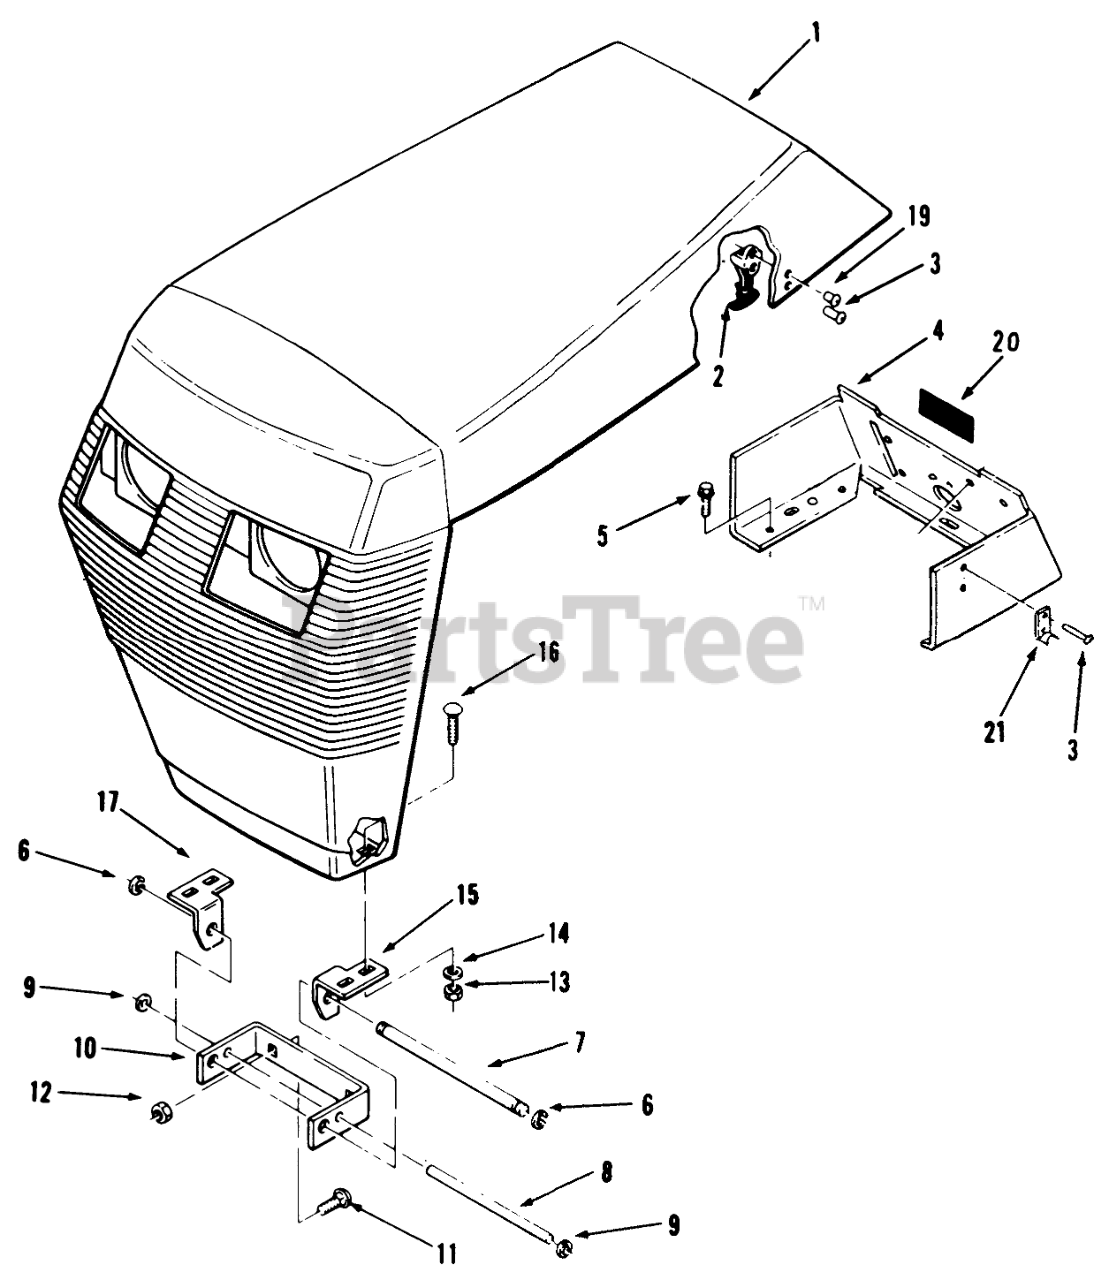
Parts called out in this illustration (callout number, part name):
1	Hood
2	HANDLE ASM
3	RIVET-POP
4	Console
5	SCREW
6	RING-RETAINING
7	ROD-GRILL PIVOT
8	ROD-HOOD STOP
9	SPEED NUT
10	Bracket-Hood Pivot
11	BOLT-CARR
12	NUT-LOCK, NI
13	NUT-LOCK, NI
14	WASHER-FLAT
15	BRKT-GRILL PIVOT R (NS)
16	SCREW-CARR
17	BRKT-GRILL PIVOT R
19	POPRIVET 1/8X 1/8 BK
20	EDGING-CONSOLE
21	KEEPER-LATCH
